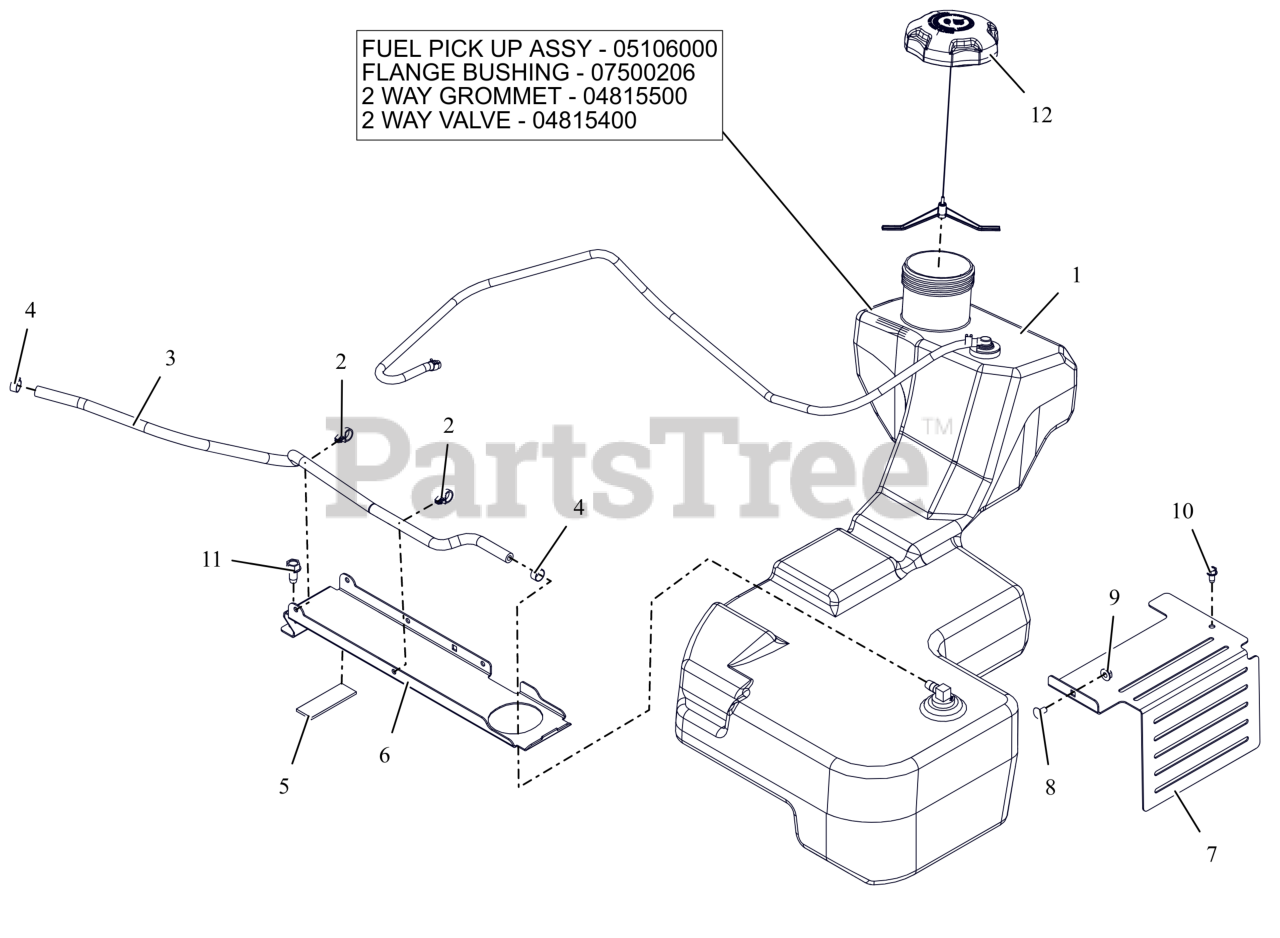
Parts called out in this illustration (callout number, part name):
1	ASM, FUEL TANK-HD
1	ASM, HD FUEL PICK-UP
1	BSHG-FLG .375X1.062X.625 NITR
1	GROMMET, 2-WAY
1	VALVE, 2-WAY
2	ROUTING CLIP (1/2" ID)
3	HOSE, .25 LOW-PERM BULK GAS
4	CLAMP, FUEL LINE
5	PAD,RBR 1.0"X3.0" W/ADHESIVE
6	BRKT, FUEL TANK HOLD DOWN
7	GUARD, TRANSAXLE FAN LH (BLACK)
8	BLT, RHSSN.25-20X.500 G5 ZCC
9	NUT-LK-CTR-FLG .25-20 ZC120
10	SCR-TAP .25-20X.50 HWH ZCC
11	SCR,TAP .375-16X.75 HWH TR ZCC
12	CAP, FUEL - 3.50 RATCHET INLET VENT
